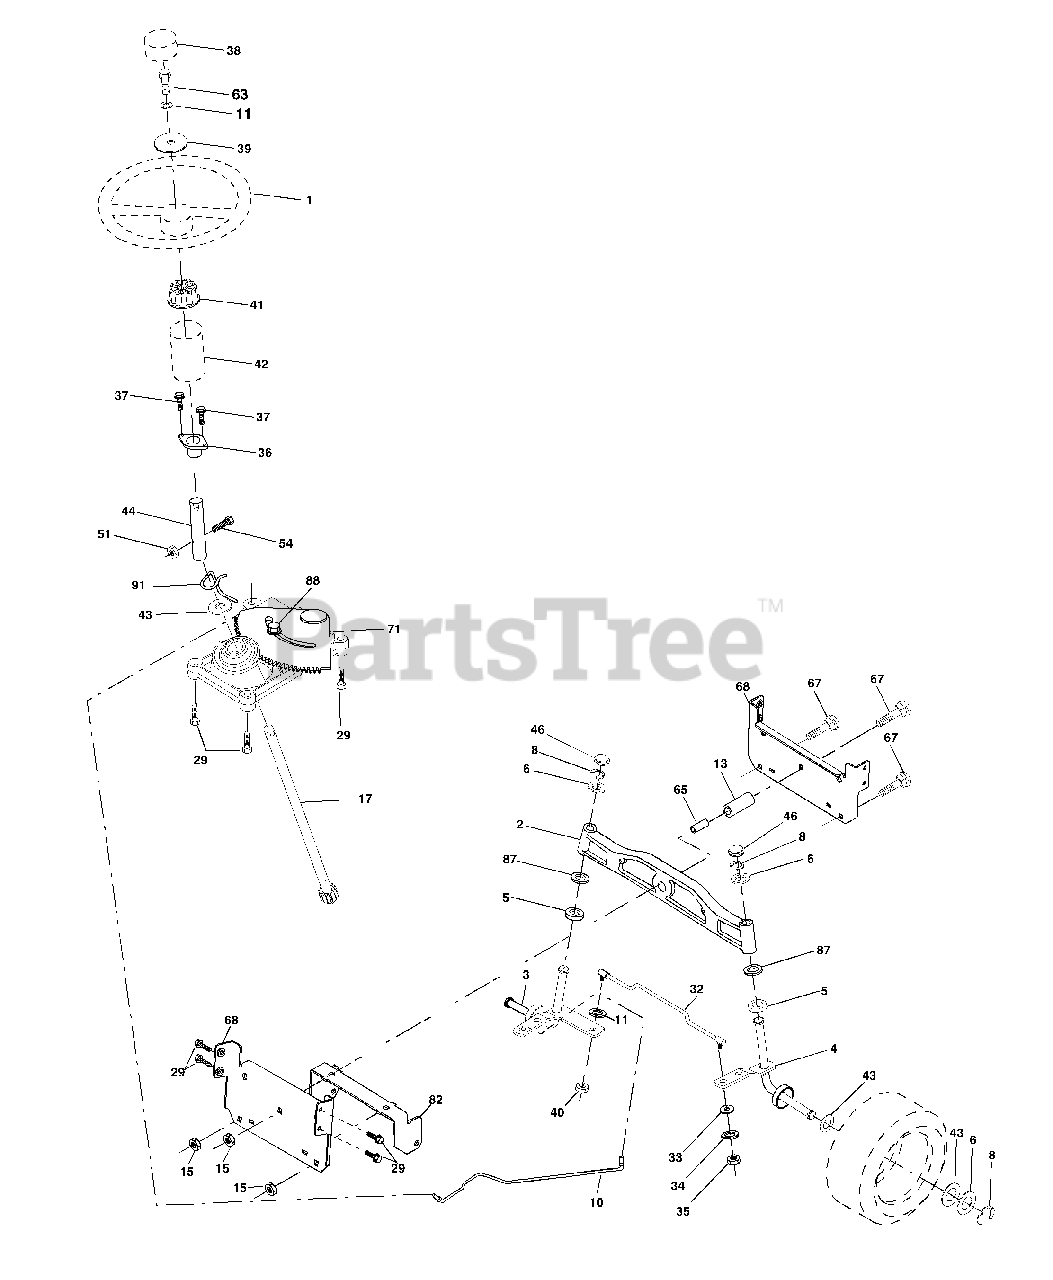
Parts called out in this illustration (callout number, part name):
1	Wheel Steering
2	Axle Asm Cast Iron LT
3	Spindle Asm LH
4	Spindle Asm RH
5	Bearing Race Thrust Harden
6	Washer 25/32 X 1-5/8 X 16 Ga
8	Ring Klip #t5304-75
10	Link Drag
11	Washer Lock Hvy Hlcl Spr 3/8
13	Spacer Brg Axle Front
15	Nut Hex Flange Lock
17	Shaft Asm Strg
29	Screw 3/8-16 x .75
32	Rod Tie
33	Washer 11/32 x 3/4 x 16 Ga
34	Washer Lock Hvy Hlcl Spr 5/16
35	Crownlock Nut 5/16-24 Unf
36	Bushing Strg
37	Screw
38	Insert Cap Strg Wh
39	Washer 13/32 X 1-1/2 X 11 Ga
40	Lock nut
41	Adaptor Wheel Strg
42	Boot Steering Dash
43	Washer 25/32 X 1 1/4 X 16 Ga
44	Extension Steering Shaft LR/LT
46	Cap Spindle Fr Top Blk
51	Nut Lock Hex w/Ins 5/16-18
54	Bolt Fin Hex 5/16-18 Unc x 1-1/4
63	Bolt Fin Hex 3/8-16unc x 1 Gr. 5
65	Spacer Brace Axle
67	Bolt Rdhd Sq 3/8-16 Unc x 2-3/4
68	Axle, Brace
71	Steering Asm.
82	Bracket Susp Chassis Front
87	Washer Flat .781 x 1 1/2 x .14
88	Bolt Shoulder 7/16-20
91	Clip Steering
